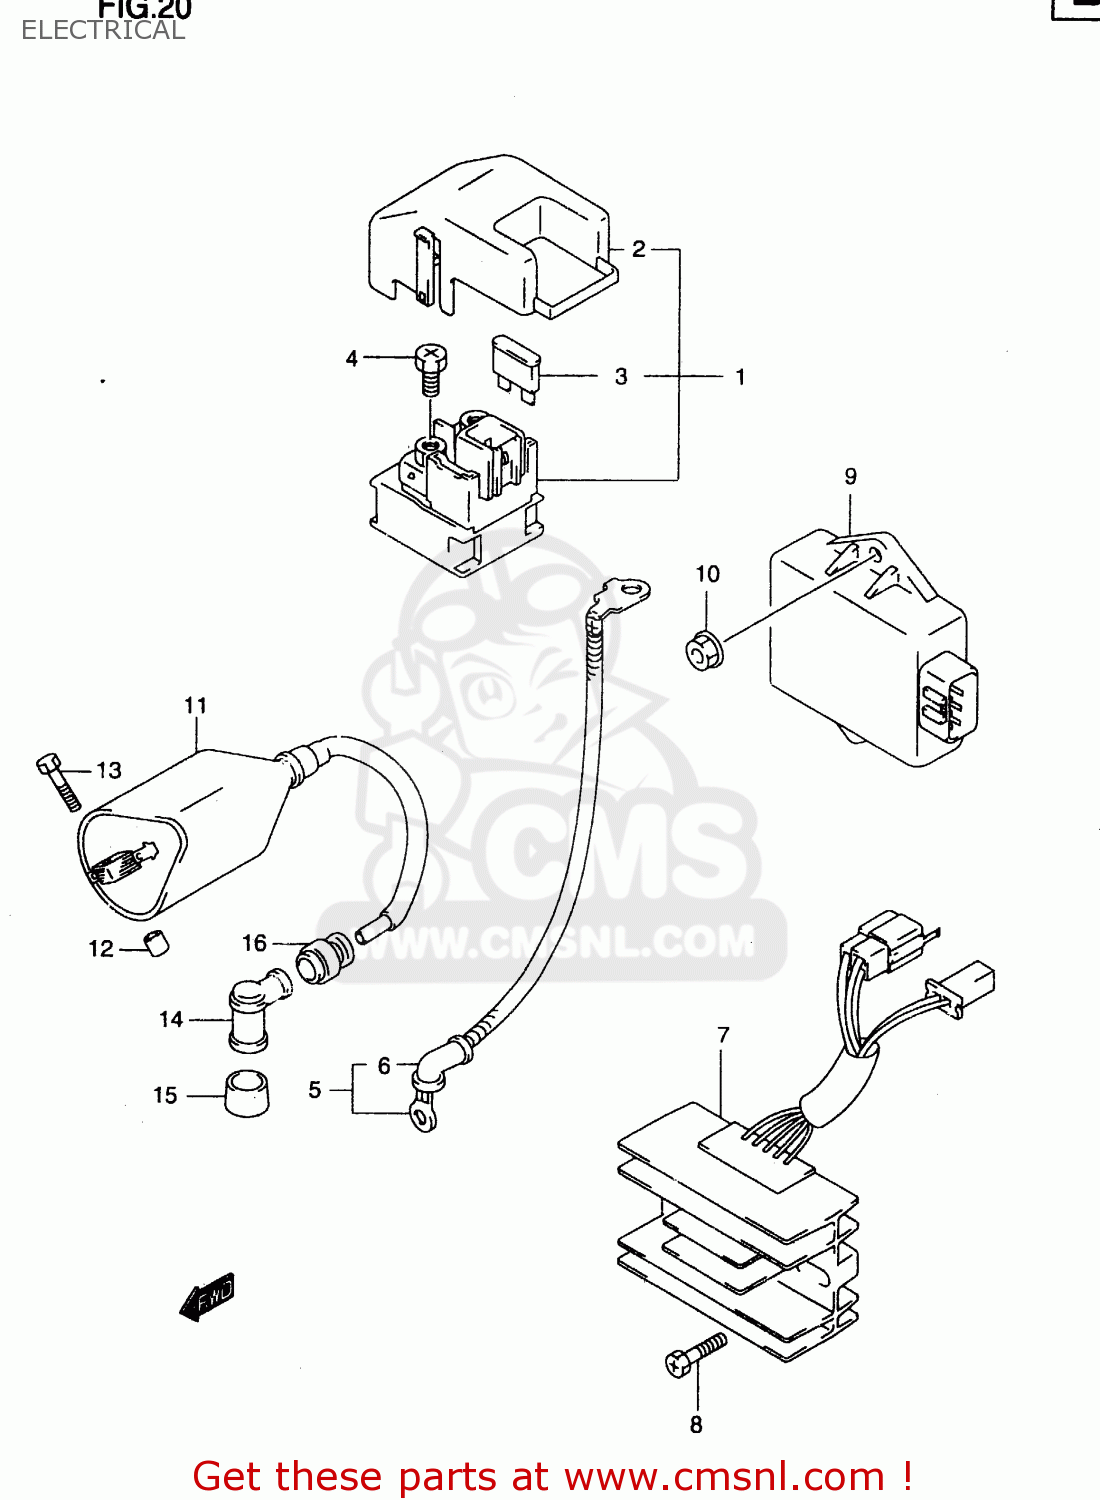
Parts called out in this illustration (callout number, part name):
1	RELAY ASSY,STARTING MOTOR
2	COVER
3	FUSE(20A)
4	SCREW(6X8)
5	WIRE,STARTER MOTOR LEAD
6	CAP,STARTER MOTOR LEAD
7	RECTIFIER ASSY
8	BOLT(6X20)
9	IGNITOR ASSY
10	NUT
11	COIL ASSY,IGNITION
12	SPACER(6.2X12X14)
13	BOLT
14	CAP ASSY,SPARK PLUG
15	SEAL,SPARK PLUG CAP
16	SEAL,HIGH TENSION CORD
